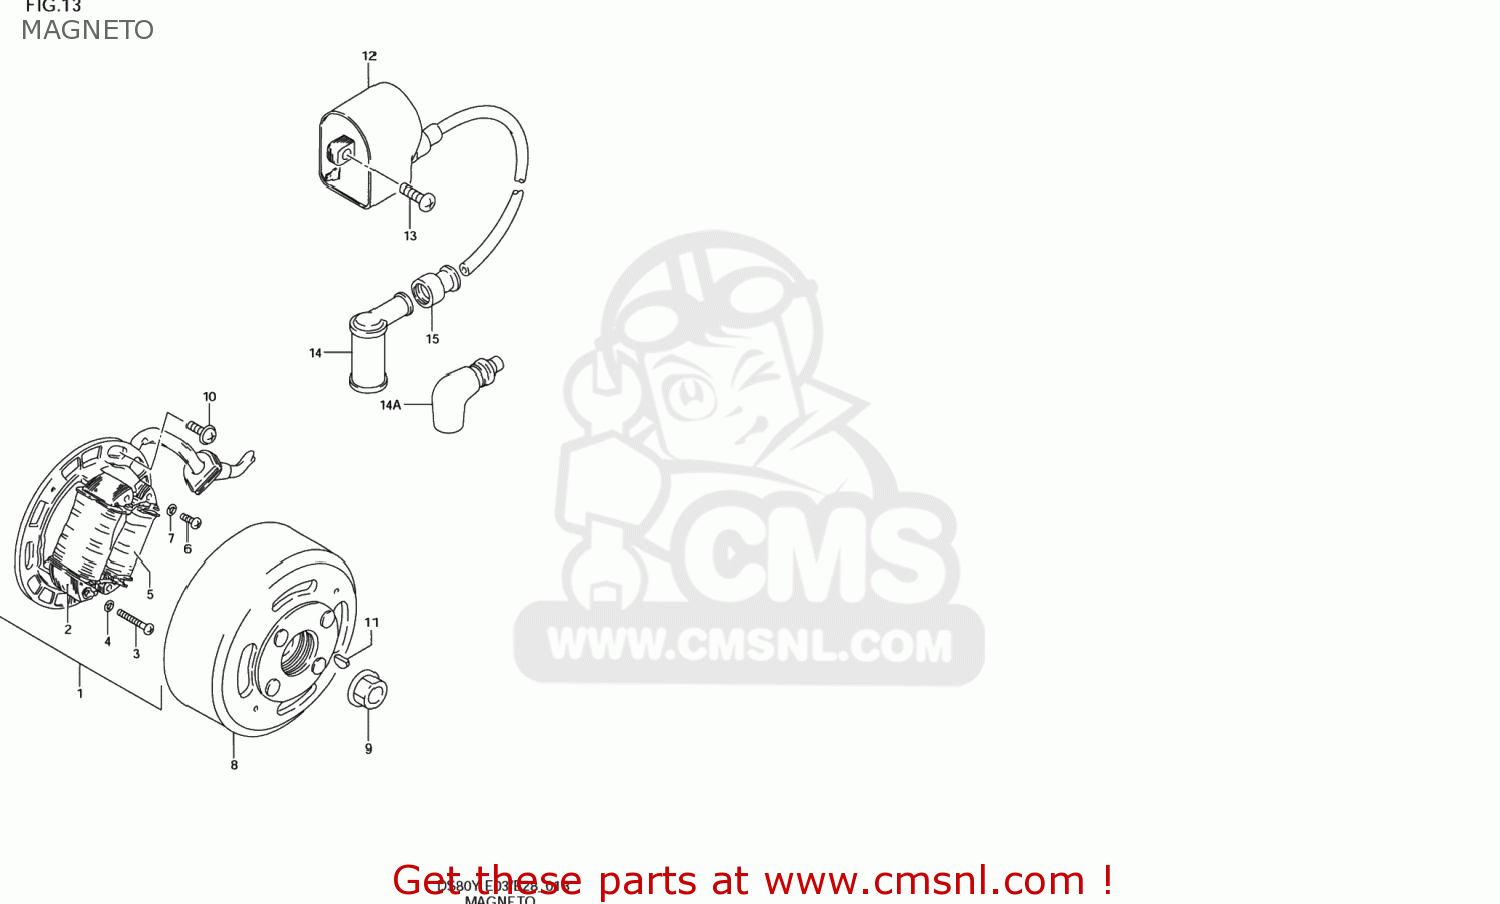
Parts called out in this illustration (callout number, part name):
1	STARTER ASSY
2	COIL,LIGHTING
3	SCREW
4	WASHER,LOCK
5	COIL,PRIMARY
6	SCREW 4X16
7	WASHER,LOCK
8	ROTOR ASSY
9	NUT
10	SCREW 5X12
11	KEY
12	UNIT & COIL ASSY,IGNITION
13	SCREW, 6X20
14	CAP,SPARK PLUG
14A	CAP,SPARK PLUG
15	SEAL,HIGH TENSION CORD
